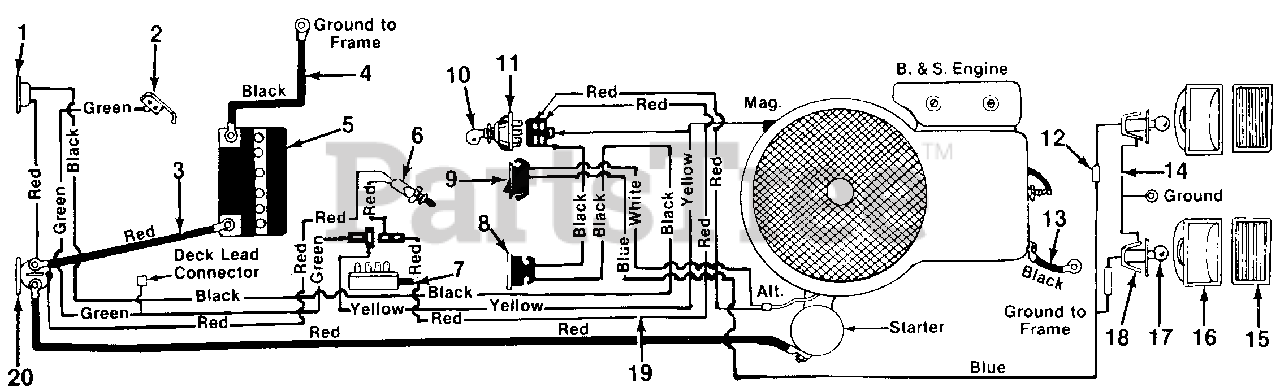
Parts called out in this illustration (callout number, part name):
1	Circuit Breaker
2	Spring-Switch
3	Electric Wire
4	Ground Wire 9.0" Lg.
5	12V-Battery
6	Safety Switch
7	Safety Switch
8	Ammeter
9	Light Switch
10	Ignition Key
11	Ignition Switch
12	Tab Receptacle
13	Ground Wire 7.25" Lg. (Black-Engine)
14	Ground Wire
15	Lens-Headlamp
16	Headlight Housing
17	Lamp
18	Headlamp Socket
19	Wire Harness
20	Solenoid
